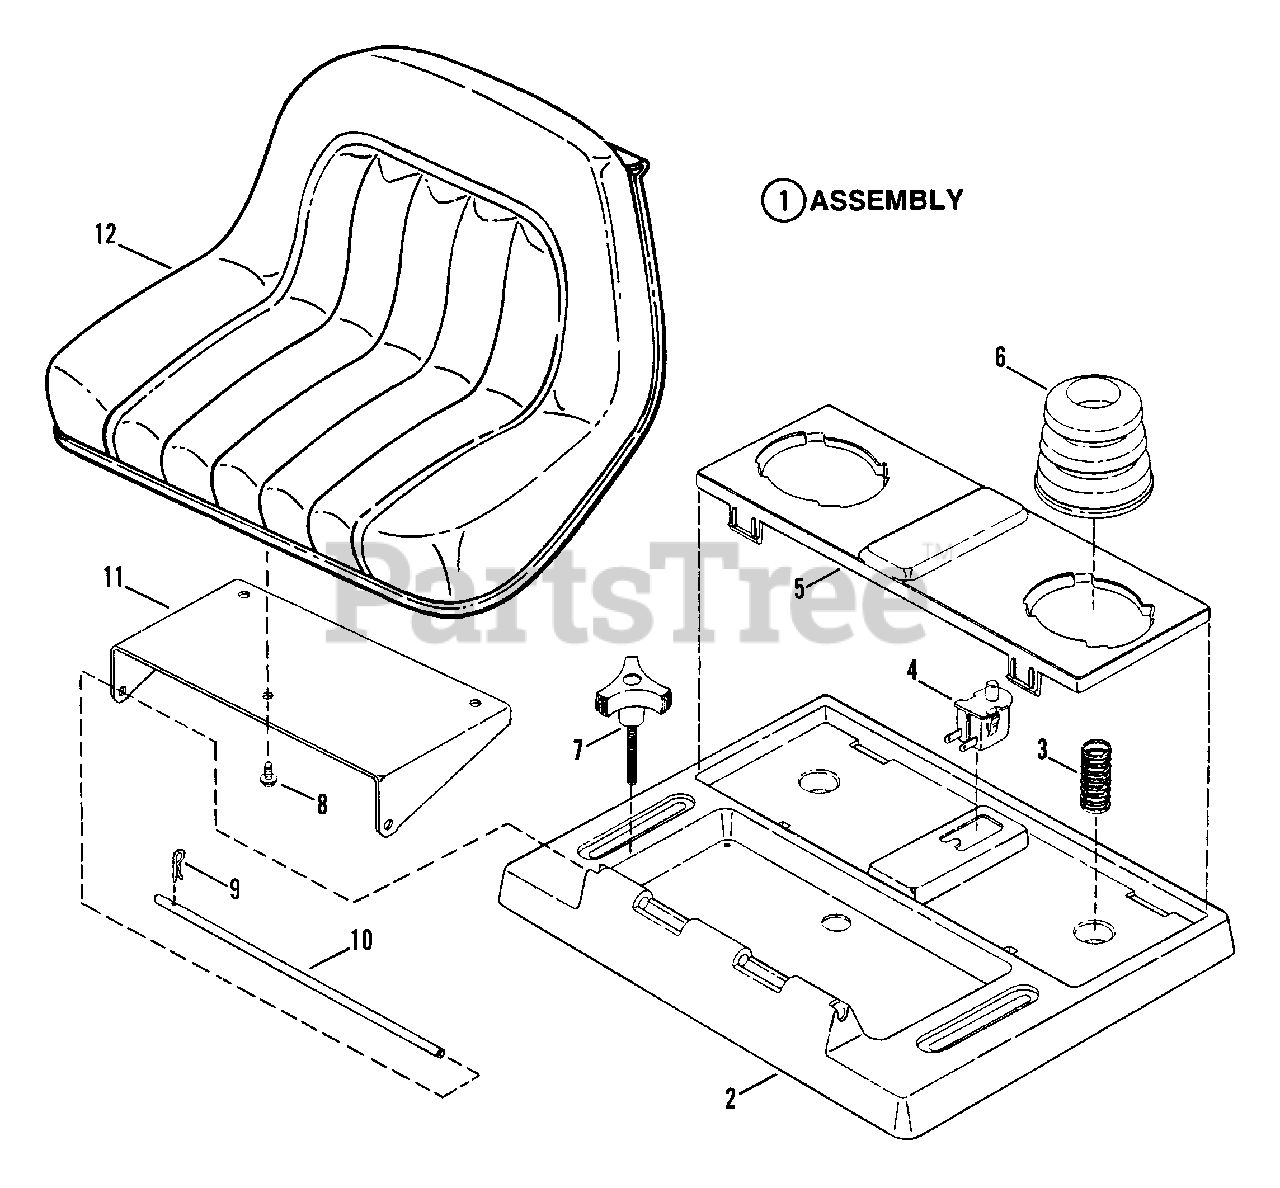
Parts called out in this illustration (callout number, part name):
1	ASSEMBLY, Seat Support
2	SUPPORT, Seat
3	SPRING
4	SWITCH, Seat (NC)
5	HOLDER, Cushion
6	CUSHION, Seat
7	KNOB, Seat Adjustment
8	BOLT, 5/16-18 x 1/2" Hex Flange Lock
9	PIN, Hair
10	ROD, Seat Hinge
11	BRACKET, Seat Support
12	SEAT, Operator's
